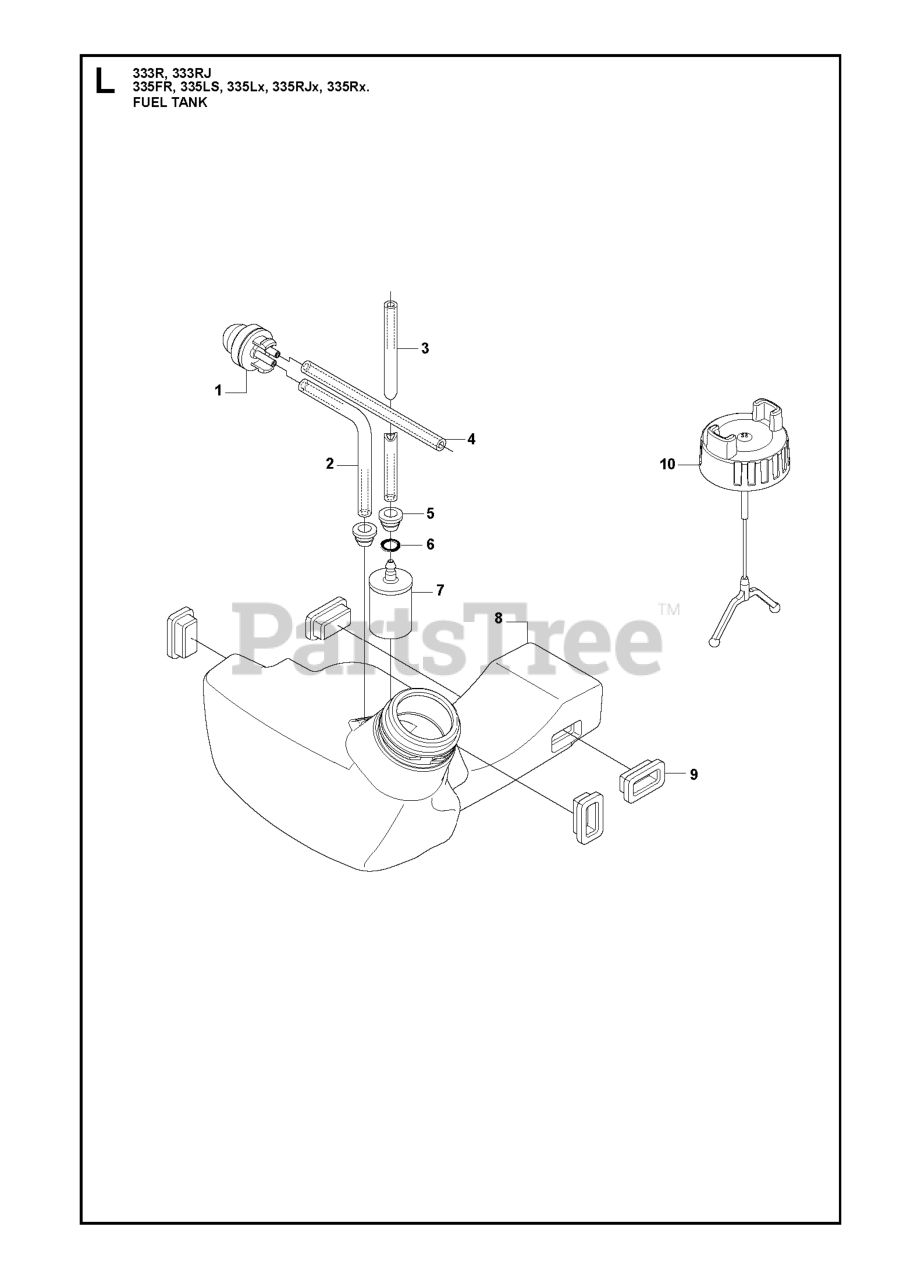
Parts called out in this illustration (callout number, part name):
1	AIR PURGE BUBBLE
5	FUEL TANK BUSHING
7	RP FUEL FILTER
10	%FUEL CAP
